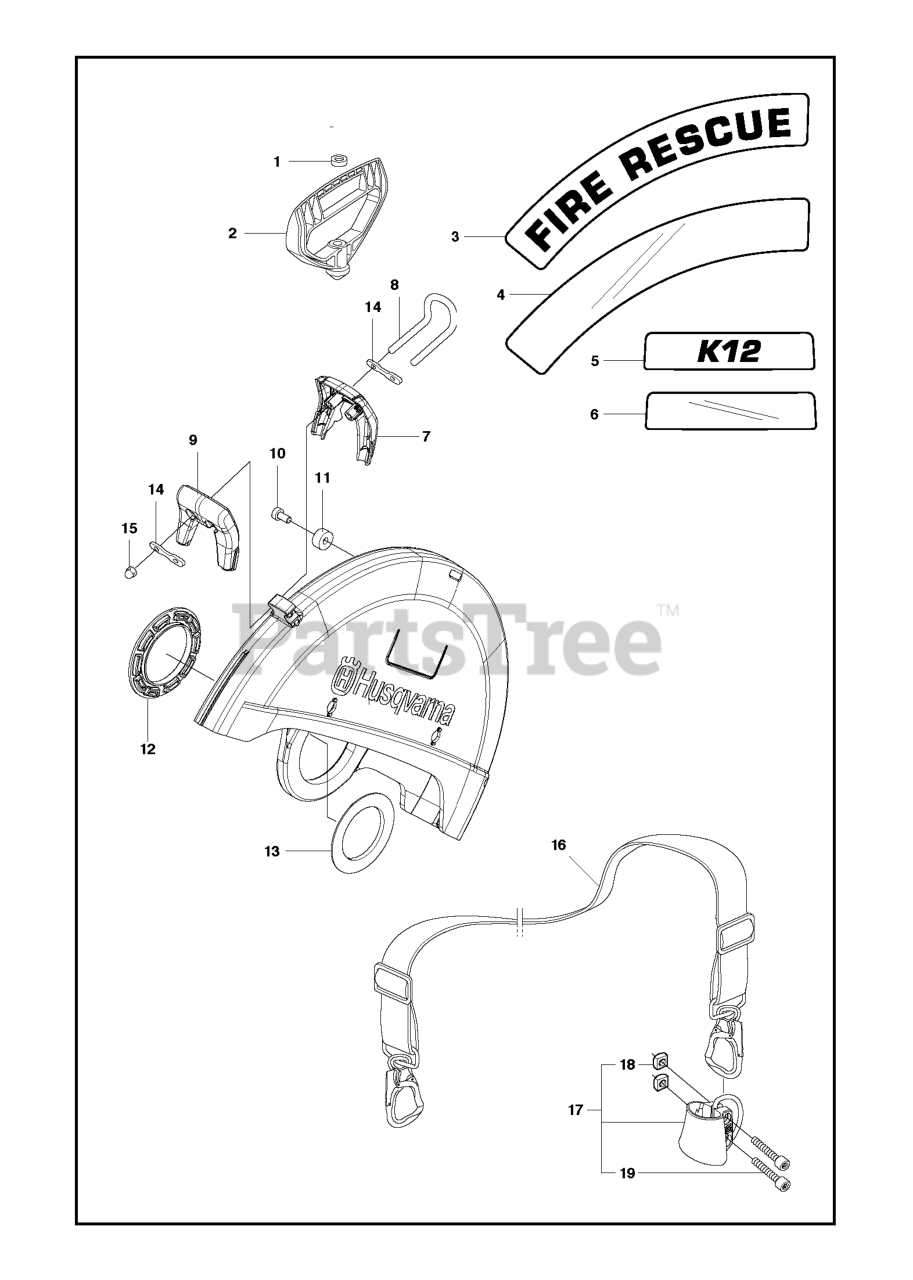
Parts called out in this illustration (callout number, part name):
3	DECAL RESCUE (R+L) BG UPPER
4	DECAL RESCUE (L) BG LOWER
5	DECAL RESCUE REAR K12
6	DECAL RESCUE REAR ROW
7	HANDLE HALF UPPER WHEEL GUARD
8	ROD RESCUE
9	HANDLE HALF
11	STOP WHEEL GUARD MG
12	LINING BEARING HOUSING
13	LINING DISC
14	HANDLE BRACKET RESCUE
15	NUT CAP MHM LOCKING M5
16	SHOULDER STRAP RESCUE
17	BRACKET RESCUE BELT K970-II K
